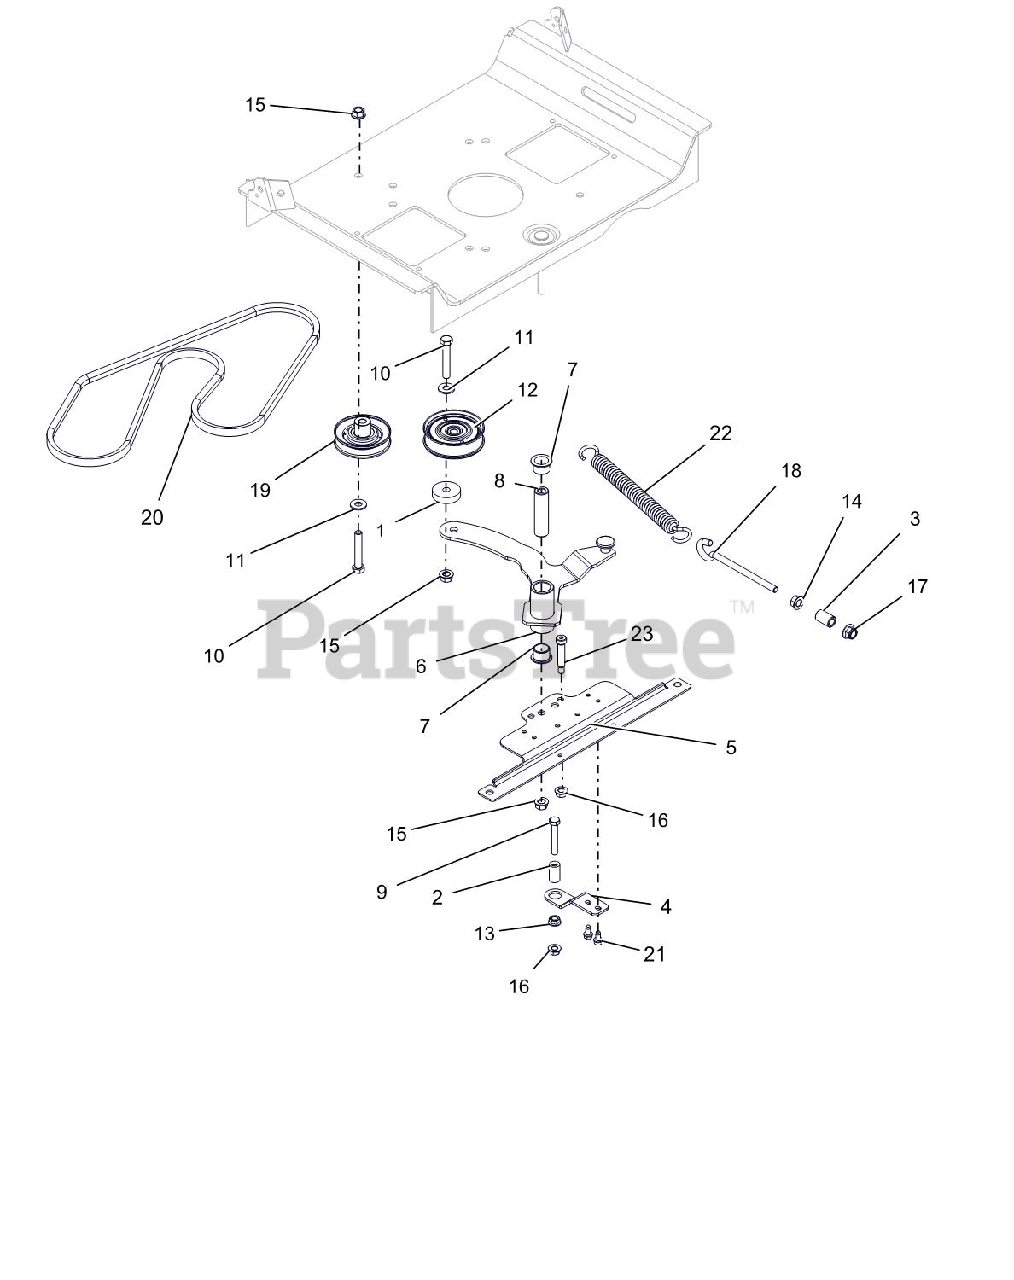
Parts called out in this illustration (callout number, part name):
1	SPACER, .39 X 1.50 X .380
2	SPACER, RUBBER 5/16 IDX1.0 LG
3	SPACER, .375X.625X.970 (PM)
4	BRKT, CLUTCH STOP
5	BRKT, DRIVE IDLER MOUNTING
6	WLDMT,GRD DRIVE IDLER ARM-LGR
7	BSHG-FLG 0.75X0.875X.625X1.125
8	BUSHING, SLEEVE .38X.750X2.78
9	@BLT-HEX .31-18X2.00 GR5 YWZC
10	@BLT-HEX .38-16X2.25 GR5 YWZC
11	@WSHR-FL-STL.38X.875X.083 YWZC
12	IDLER, FLAT - 3.05" X .75"
13	@NUT-SPNLK-FLG .312-18 YWZC
14	@NUT-SPNLK-FLG .375-16 YWZC
15	@NUT-LK-TOP-FLG .38-16 YWZC
16	@NUT-LK-TOP-FLG .31-18 YWZC
17	@NUT-LK-NYL-FLG .38-16 YWZC
18	BOLT,.38-16 X 4.25-.62 DIA EYE
19	ASM, 3.00" V IDLER
20	V-BELT, A-RAW EDGE
21	SCR-TAP .25-20X.50 HWH TR YWZ
22	SPRING, EXTENSION
23	BLT-SHLDR .38X1.5X.31-18 SLT Y
